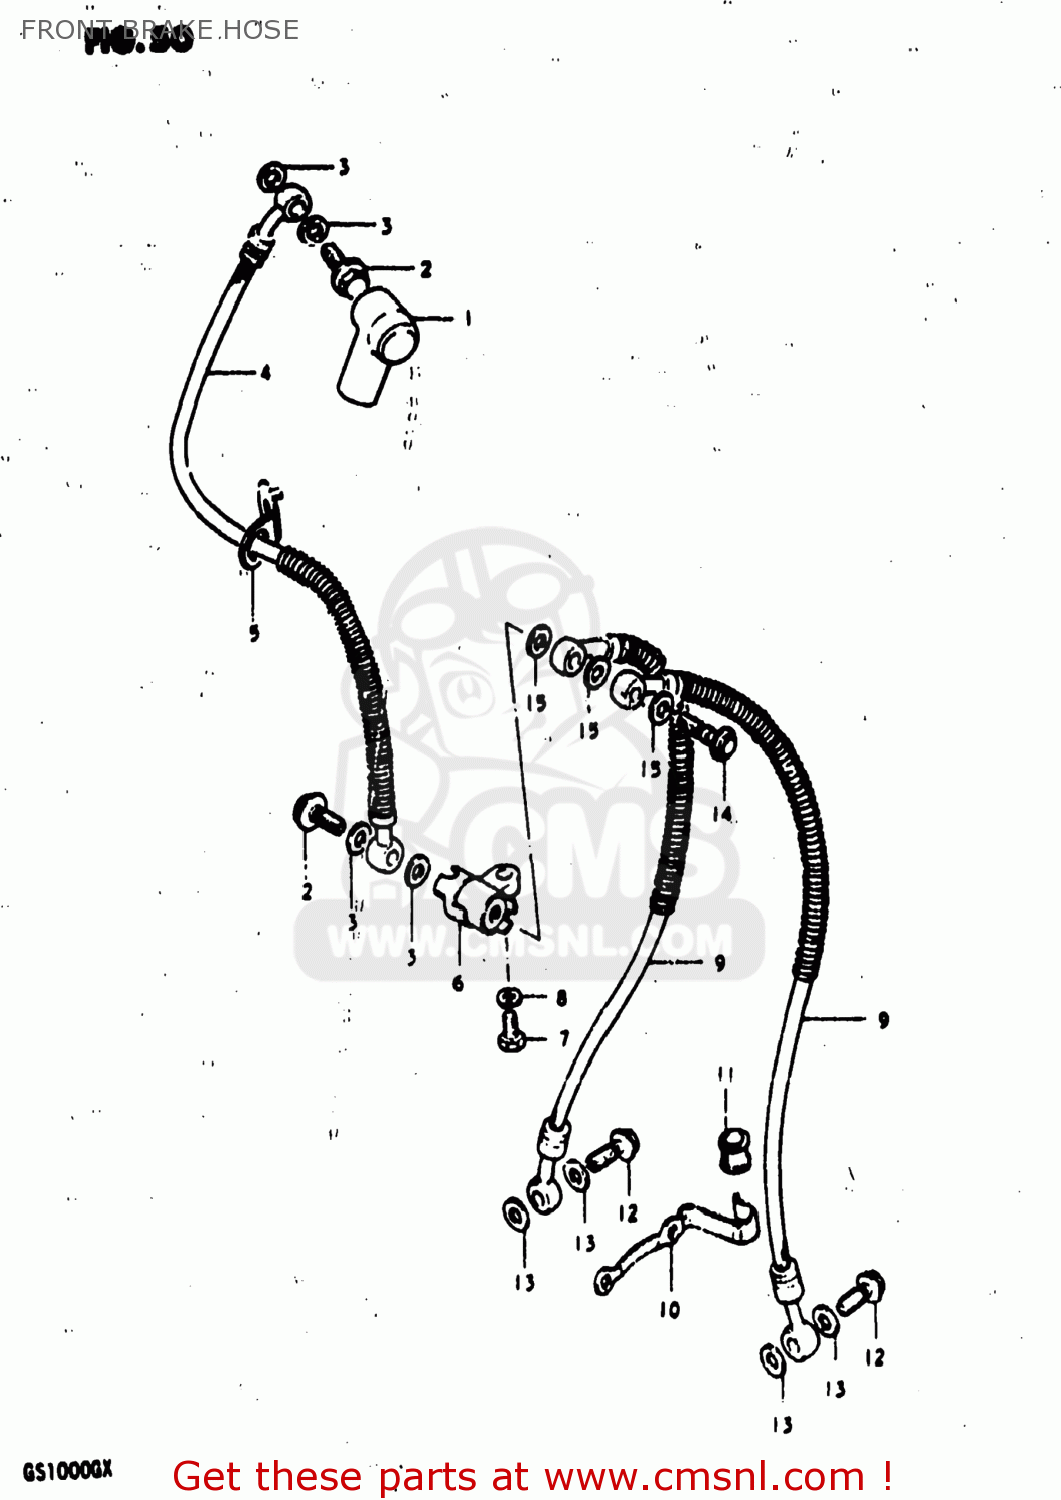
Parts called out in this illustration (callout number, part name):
1	BOOT,MASTER CYLINDER
2	BOLT,UNION
3	WASHER
4	HOSE,FRONT BRAKE
5	GUIDE,BRAKE HOSE NO.1
6	JOINT,BRAKE HOSE
7	BOLT
8	LOCK WASHER
9	HOSE,FRONT BRAKE
10	GUIDE,BRAKE HOSE NO.2
11	BUSH,BRAKE HOSE GUIDE,NO.2
12	BOLT,UNION
13	WASHER
14	BOLT,UNION
15	WASHER
